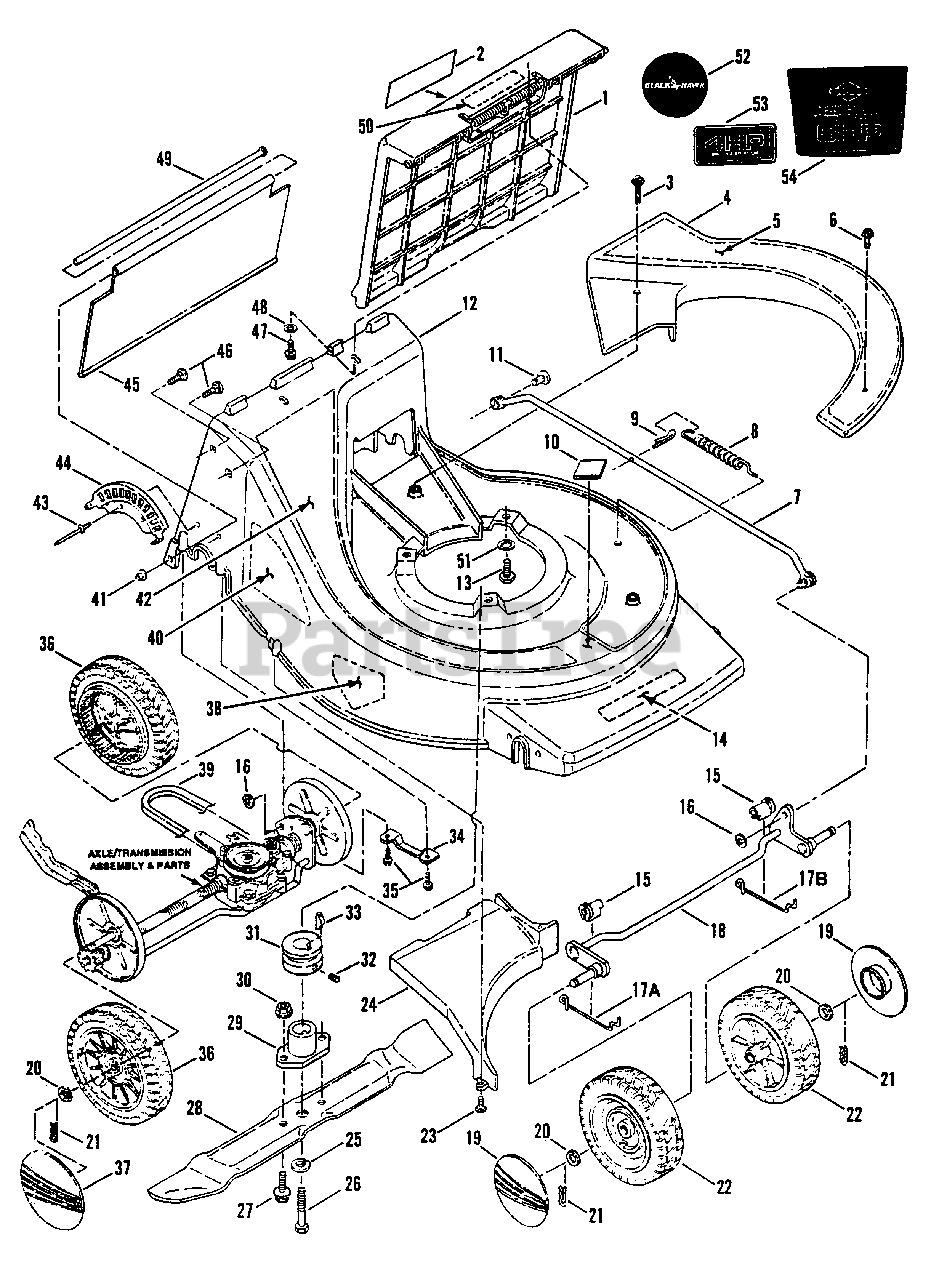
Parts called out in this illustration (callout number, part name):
1	ASSEMBLY, Discharge Door
2	DECAL, Discharge Door
3	SCREW, #10-24 x 1-1/2 Slotted, Hex Washer Head, Self-Tapping
4	COVER, Belt/Tie Bar
5	DECAL, Felt Cover
6	SCREW, #10-24 x 1" Slotted, Hex Washer Head, Self-Tapping
7	ASSEMBLY, Tie Bar
8	SPRING, Tie Bar
9	COTTER-PIN, 1/8 x 3/4"
10	DECAL, Premium Quality Medallion
11	PIN, Tie Bar, 3/8 x 5/8"
12	DECK, 21" Cast Aluminum
13	SCREW, 3/8-16 x 1" Hex Head, Self-Tapping
14	DECAL - BLACKHAWK
15	BUSHING, Front Axle
16	RETAINER, Wheel
17A	SPRING, Axle Retainer (Right Hand)
17B	SPRING, Axle Retainer (Left Hand)
18	ASSEMBLY, Front Axle
19	HUB-CAP, Front Wheels
20	WASHER, 1/2" Flat
21	HAIRPIN, .062 x .900"
22	ASSEMBLY, Wheels (Front)
23	SCREW, #10-24 x 5/8" Slotted, Hex Washer Head, Self-Tapping
24	BAFFLE, Discharge
25	WASHER, Split Lock (Heavy)
26	SCREW, 3/8-24 x 1-3/4" Hex Head Cap, Grade 5
27	BOLT, 3/8-16 x 1-1/4" Hex Flng. Lock
28	BLADE, 21" Bagging
29	HUB, Blade Drive, 25mm
30	NUT, 3/8-16 Hex Nyloc
31	PULLEY, Traction Drive, 25mm
32	SETSCREW, 5/16-18 x 5/16" Hex Socket
33	KEY, #HP-506 Hi-Pro
34	SUPPORT, Rear Axle
35	SCREW, 1/4-20 x 5/8" H.W.H., Self-Tap.
36	ASSEMBLY, Wheels (Drive)
37	HUB-CAP, Rear Wheels
38	DECAL - DANGER
39	BELT, Traction Drive
40	DECAL, Height Adjustment
41	PUSH-NUT, 1/4"
42	DECAL, Mulching
43	RIVET, 3/16 x 1/2" Steel
44	PLATE, Height Adjustment
45	SHIELD, Trailing
46	SCREW, 5/16-18 x 1" Carriage, Grade 5
47	SCREW, 1/4-20 x 5/8" Truss Head, Torx
48	WASHER, 1/4 Flat
49	ROD, Training Shield
50	DECAL - WARNING
51	WASHER, 7/16 Internal Tooth Lock
52	DECAL - BLACKHAWK, Recoil Cover
53	DECAL, 4HP
54	DECAL, 5HP
